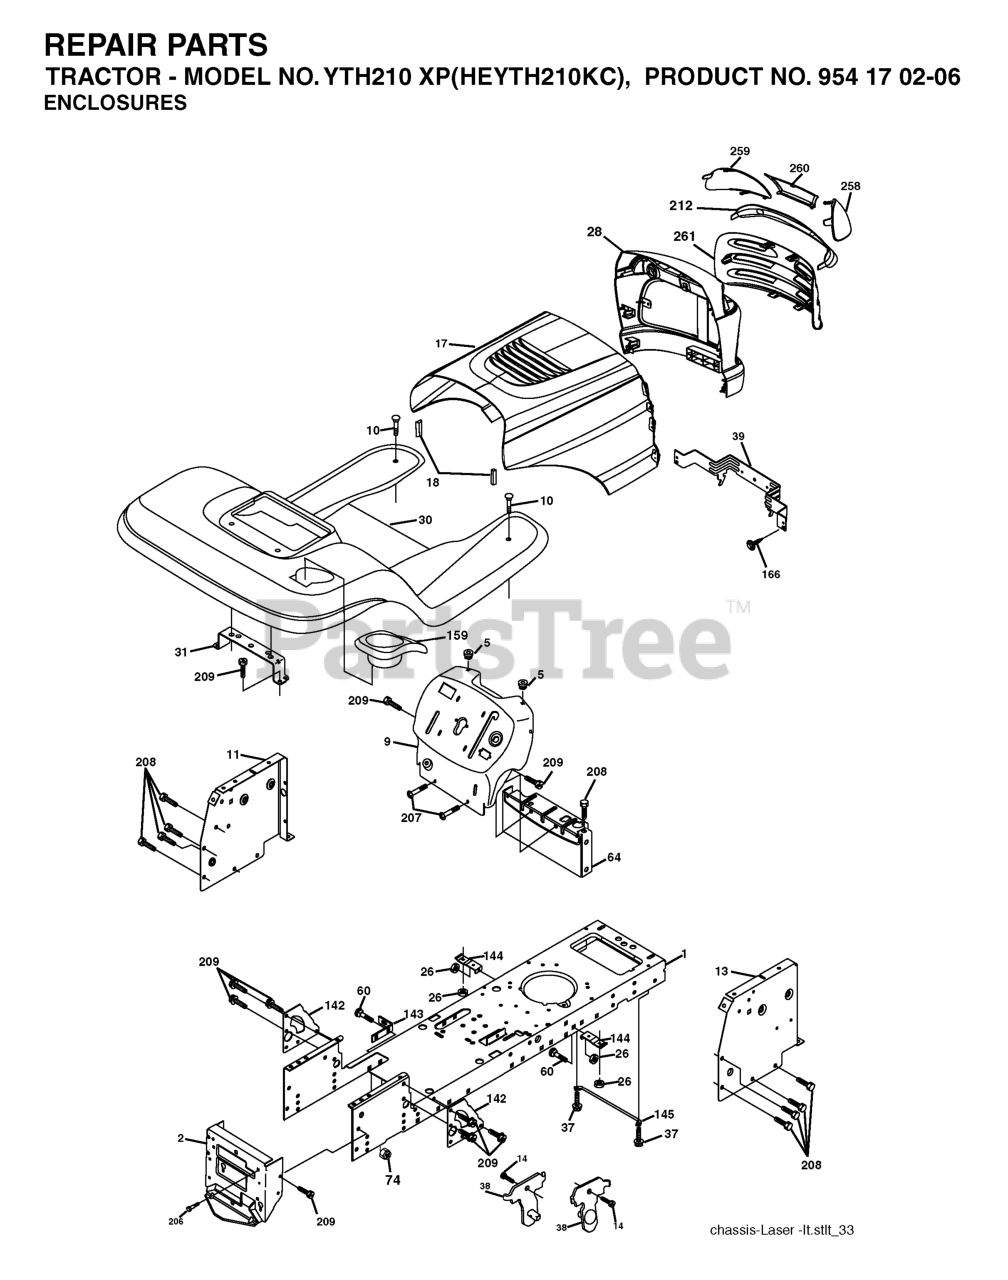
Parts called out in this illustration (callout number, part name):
1	CHASSIS STAMPING
2	DRAWBAR, 12GA
5	BUMPER.RUBBER.HOOD
10	BOLT D
11	PANEL.DASH.LH.LTX
13	PANEL ASM, DASH RH
17	VENT.HOOD.LASER.III
18	BUMPER.HOOD.LARGE.1.75"
20	PLATE MTG.BATTERY/FUEL TANK
23	BUSHING.SNAP.NYL.BLK.
26	NUT
30	FENDER
31	BRACKET.SUPPORT.FENDER
37	Screw 5/16-18 x 1/2 Hex, Self Tapping 5/16-18 x 1/2
38	BRACKET.ASM.PIVOT.MOWER.REAR
39	BRACKET PIVOT LASER
60	Bolt - Rd. Hd. Sq. Neckiage 3/8 16 x 3/4
64	DASH LOWER
90	NUT.PUSH.3/16
142	PLATE REINFORCEMENT
143	BRACKET, SWAYBAR CHASSIS
144	BRKT, FOOT REST
145	ROD PIVOT CHASSIS/HOOD
159	GREY CUP HOLDER
166	SCREW
206	SHOULDER BOLT 5/16-18TT
207	SCREW, 5/16-18 X 1/2
208	SCREW 3/8-16X1/2
209	SCREW, 3/8-16X3/4
212	INSERT.LENS.REFLECTIVE
217	CONSOLE FUEL WINDOW
219	SCREW
258	LENS LH
259	LENS LH
260	COVER.LENS.HUSQ.LASER
272	VENT.HOOD.LASER.
273	VENT.HOOD.LASER.
